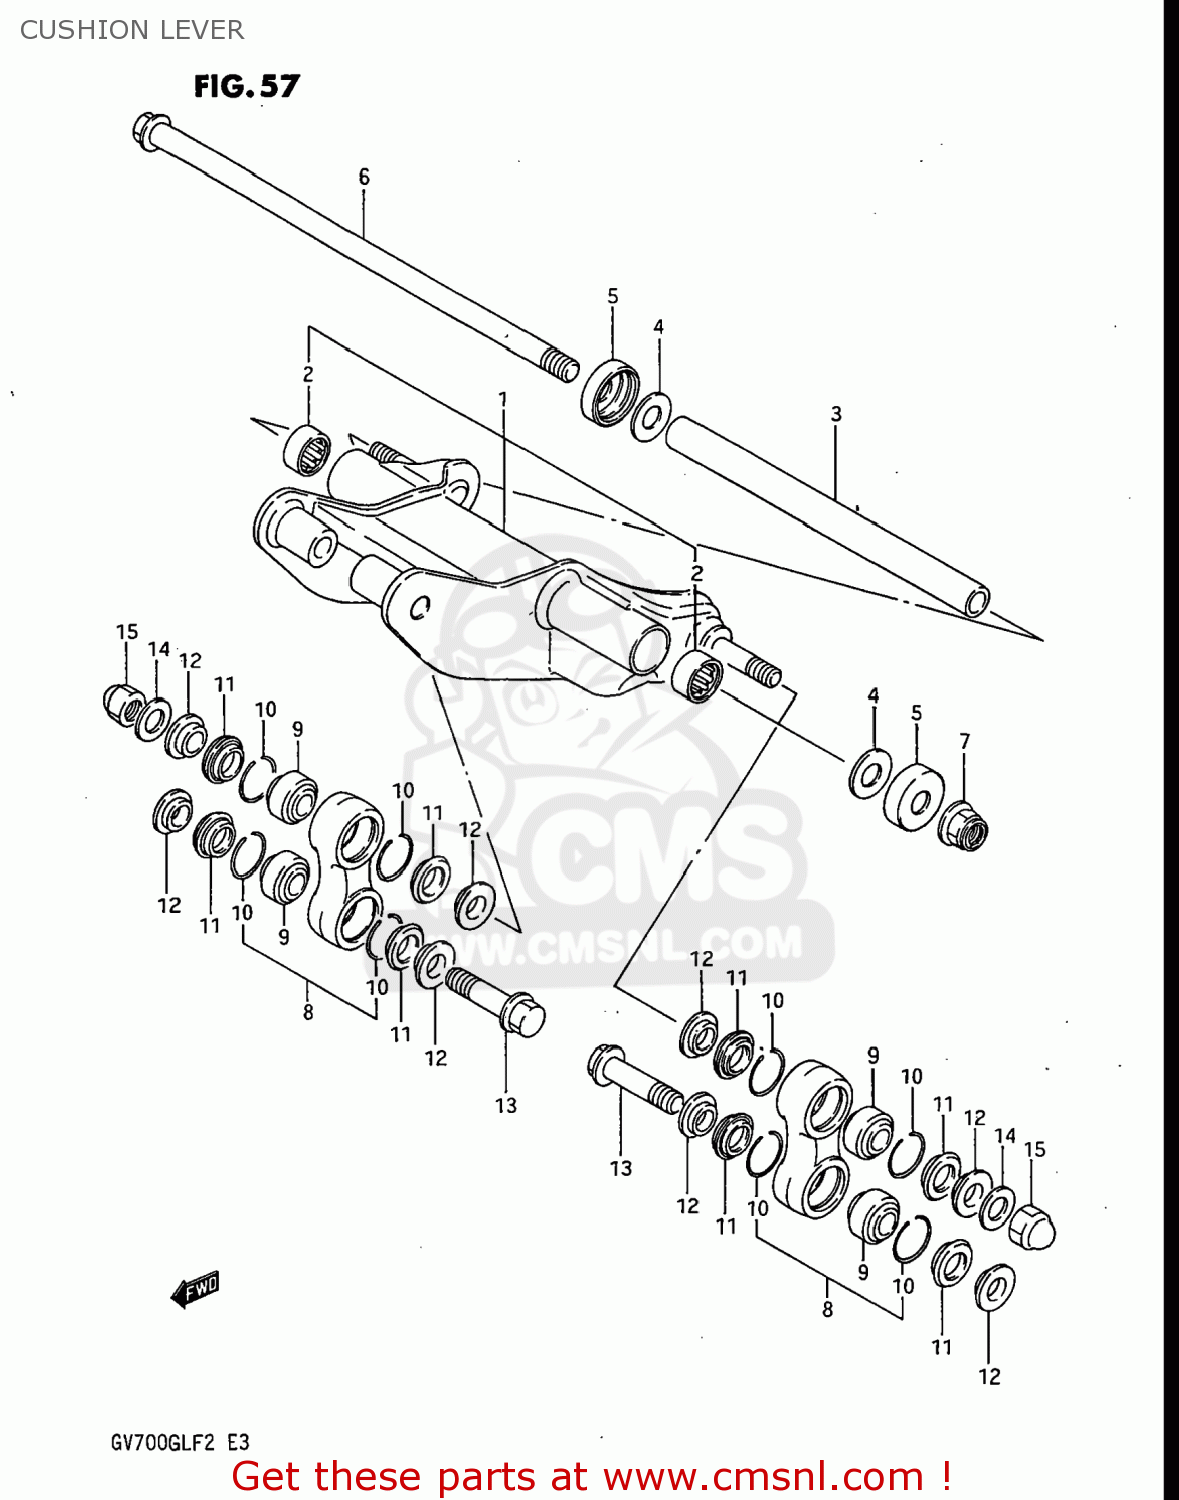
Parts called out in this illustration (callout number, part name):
1	LEVER SET,REAR CUSHION
2	ROLLER BEARING (17X24X25)
3	SPACER,REAR CUSHION LEVER
4	WASHER
5	COVER,RR SWGARM DUST SEAL
6	SHAFT,REAR CUSHION LEVER
7	NUT 12MM
8	LEVER SET,REAR CUSHION
9	BEARING(12X26X16)
10	RING,STOPPER
11	SEAL,RR CUSHION ROD DUST
12	SPACER,RR CUSHION ROD
13	BOLT,REAR CUSHION LEVER
14	WASHER
15	NUT
